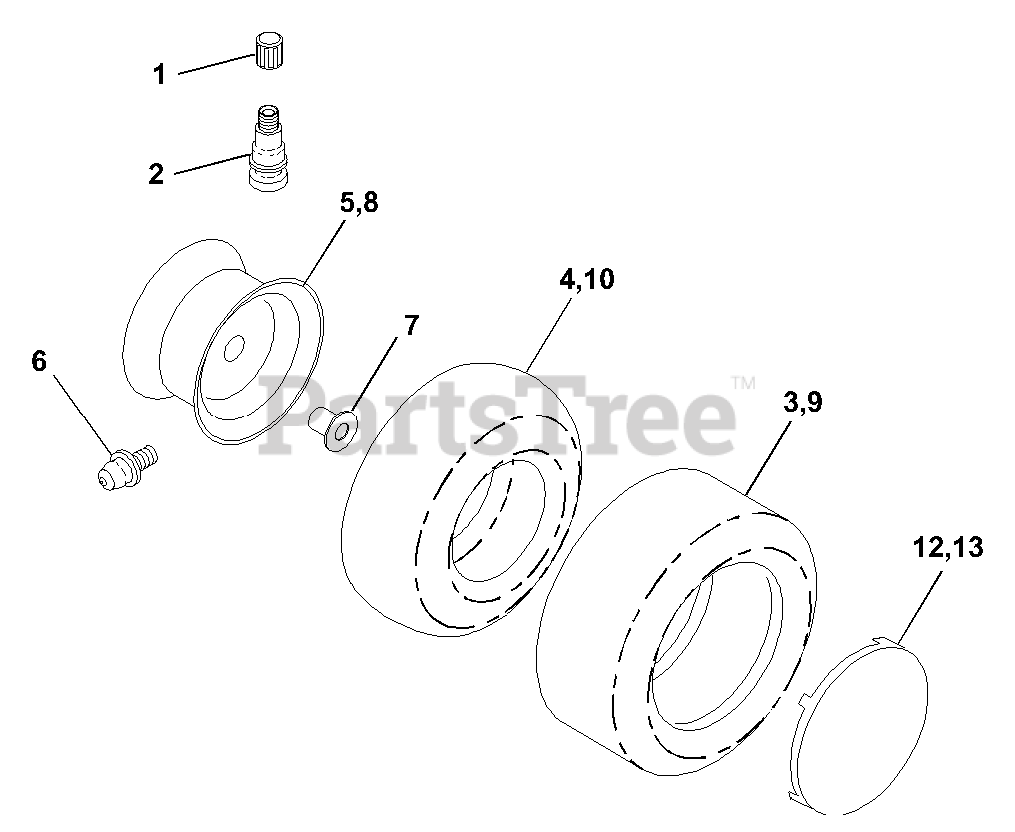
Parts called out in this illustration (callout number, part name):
2	VALVE STEM LT
3	TIRE HEAVY DUTY
4	TUBE.5.3/4.5/6
5	RIM FRONT 6"
6	FITTING LT
7	BEARING T
8	RIM.ASM.8X7.REAR.WHITE
9	TIRE.TS.20X10-8
10	TUBE
12	COVER.FRONT.WHEEL
13	CAP,HUB REAR
